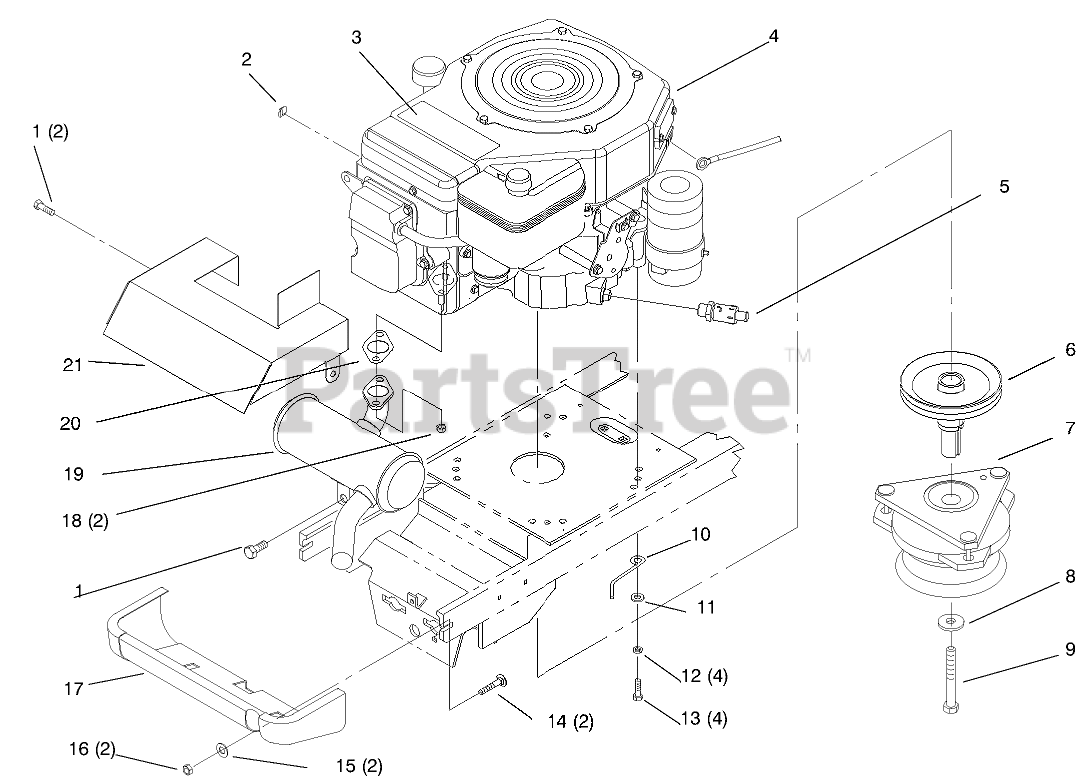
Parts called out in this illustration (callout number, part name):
1	SCREW-HWHTF
2	CLIP-RETAINER, WIRE
3	DECAL - LOGO
4	ENGINE - KOHLER 15
5	VALVE-DRAIN, OIL
6	PULLEY- ENGINE GEAR
7	CLUTCH - PTO
8	WASHER
9	SCREW-HH
10	GUIDE-BELT
11	WASHER-PLAIN
12	WASHER-LOCK
13	SCREW-CAP, HH
14	BOLT-CARR
15	WASHER-FLAT
16	NUT-LOCK, NI
17	Shield-Muffler
18	NUT-HF
19	Muffler
20	Gasket-Exhaust
21	SHIELD-MUFFLER
